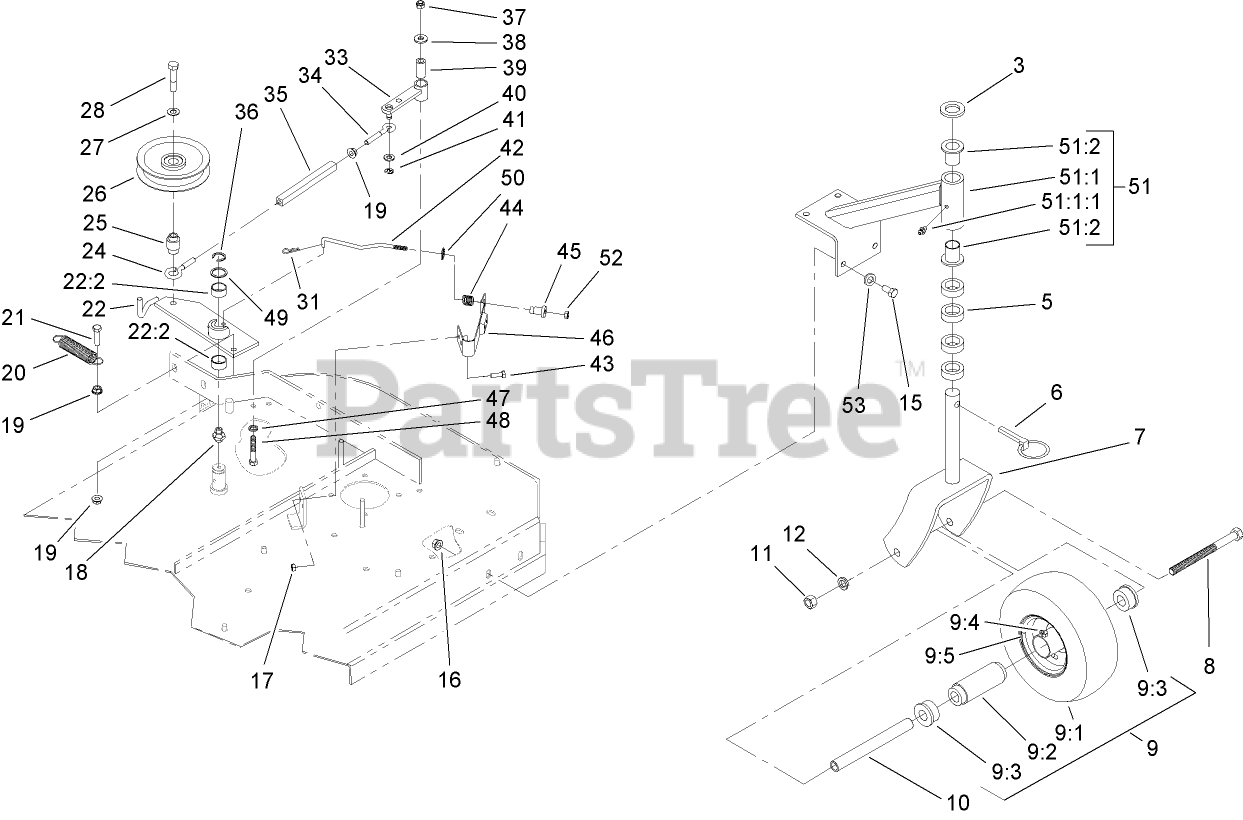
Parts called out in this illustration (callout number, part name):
3	WASHER-FLAT
5	SPACER-CASTER
7	FORK
8	SCREW-HH
9	WHEEL AND TIRE ASM
9:1	Tire
9:2	BEARING
9:3	BUSHING
9:4	FITTING-GREASE
9:5	Wheel
10	SPACER
11	NUT-HH
12	WASHER-LOCK
15	SCREW-HH
16	NUT-HHF, WHIZ
17	NUT-LOCK, NI
18	FITTING-GREASE
19	NUT-HF
20	SPRING-EXTENSION
21	SCREW-HH
22	Idler Arm ASM
22:2	SLEEVE-BEARING
24	EYEBOLT-THREAD, LH
25	BUSHING-ENGAGEMENT
26	PULLEY-IDLER
27	WASHER-BELLEVILLE
28	SCREW-HH
31	PIN-COTTER
33	ARM-ASSIST
34	EYEBOLT-THREAD, RH
35	BODY-TURNBUCKLE
36	RING-RETAINING, EXT
37	NUT-LOCK, NI
38	WASHER-FLAT
39	TUBE-PIVOT
40	WASHER-PLAIN
41	RING-RETAINING, EXT
42	Rod-Brake
43	SCREW-HH
44	SPRING-COMPRESSION
45	SPACER-FLANGED
46	PAD AND SPRING ASM
47	WASHER-SPRING
48	SCREW-HH
49	WASHER-SPINDLE
50	RING-PUSH ON
51	SUPPORT ASM
51:1	Support-Caster
51:1:1	FITTING-GREASE
51:2	BEARING-FLANGED
52	NUT-LOCK, NI
53	WASHER-FLAT
